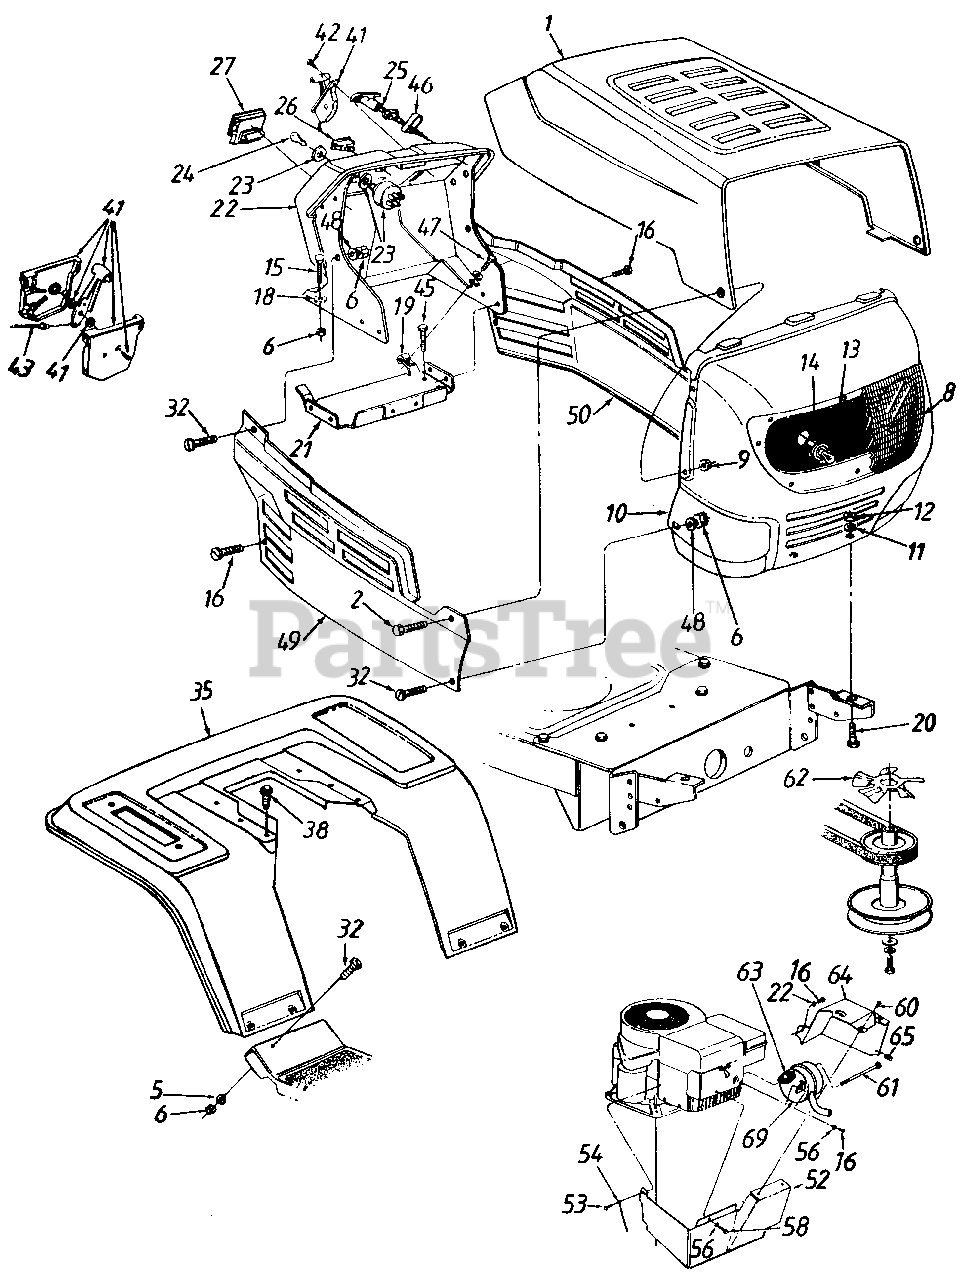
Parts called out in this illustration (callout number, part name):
6	Hex Nut 1/4-20 Thd.
9	Flange L-Nut 1/4-28 Thd.
11	Fl-Wash. .344" I.D. x 1" O.D.
12	Hex Nut 5/16-18 Thd.
13	Lamp
14	Socket
15	Carriage Bolt 1/4-20 x .75" Lg.
16	Hex Wash. Hd. TT-Tap Scr. 1/4-20 x .5" Lg.
18	Bolt Retainer 1/4" I.D.
19	Speed Nut 1/4-20 Thd.
20	Hex Bolt 5/16-18 x .75" Lg.
23	Ignition Switch
24	Ignition Key
25	Choke Control
26	Light Switch
27	Ammeter
32	Truss Mach. Scr. 1/4-20 x .5" Lg.
41	Throttle Box Ass'y.
42	Truss Mach. AB-Tap Scr. #10 x .5" Lg.
43	Throttle Control Wire
45	Hex Wash. Hd. B-Tap Scr. 5/16-18 x .5" Lg.
46	Choke Retainer
47	Hex TT-Tap Scr. 1/4-20 x .75" Lg.
48	Bell-Wash. .265" I.D. x .75"
49	Lens
53	Truss Mach. Scr. 5/16-18 x .75" Lg.
54	Ground Wire
56	Spr. Wash. 1/4" I.D.
58	Hex Bolt 1/4-20 x 3/8" Lg.
60	Hex B-Tap Scr. #10 x .38" Lg.
61	Shoulder Bolt
63	Exhaust Gasket
69	Muffler
